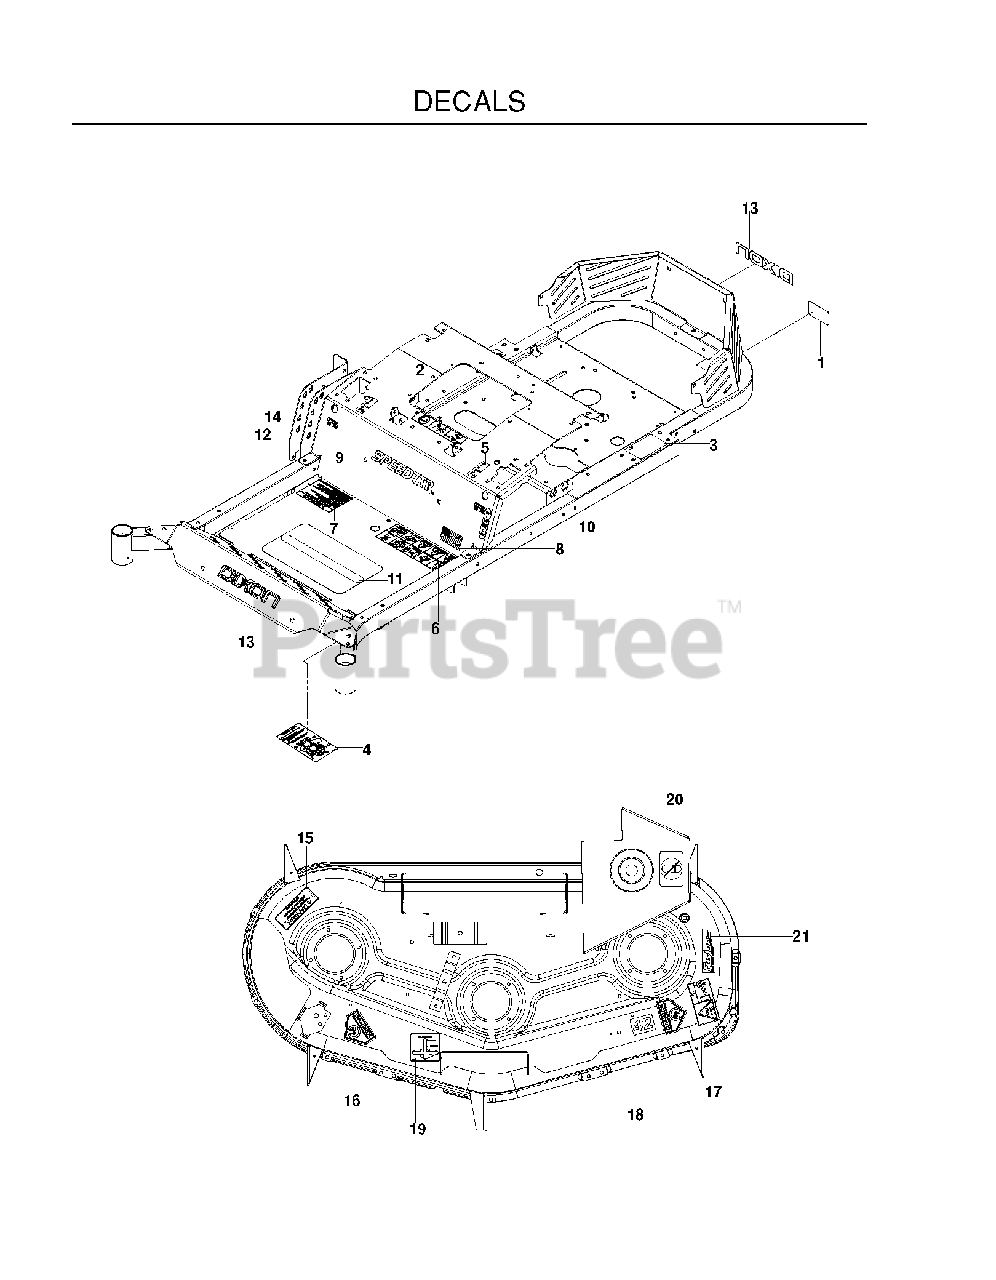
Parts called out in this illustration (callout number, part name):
1	DECAL, PROP. 65
2	DECAL, BATTERY
3	DECAL, DO NOT MOUNT
4	DECAL, SERVICE
5	DECAL, MOTION CONTROL
6	DECAL, SAFETY WARNING
7	DECAL, WARNING
8	DECAL, FLAG
9	DECAL, SPEEDZTR, 8"
10	DECAL, PARK BRAKE
11	ANTI-SKID PAD
12	DECAL, HEIGHT
13	DECAL, DIXON LOGO, DOMED
14	DECAL, F.S.T.
15	DECAL, DANGER
16	DECAL, CPSC
17	DECAL, EURO SEVERING
18	DECAL, 42
19	DECAL, BELT ROUTING
20	DECAL, NO STEP
21	DECAL, FUSION
